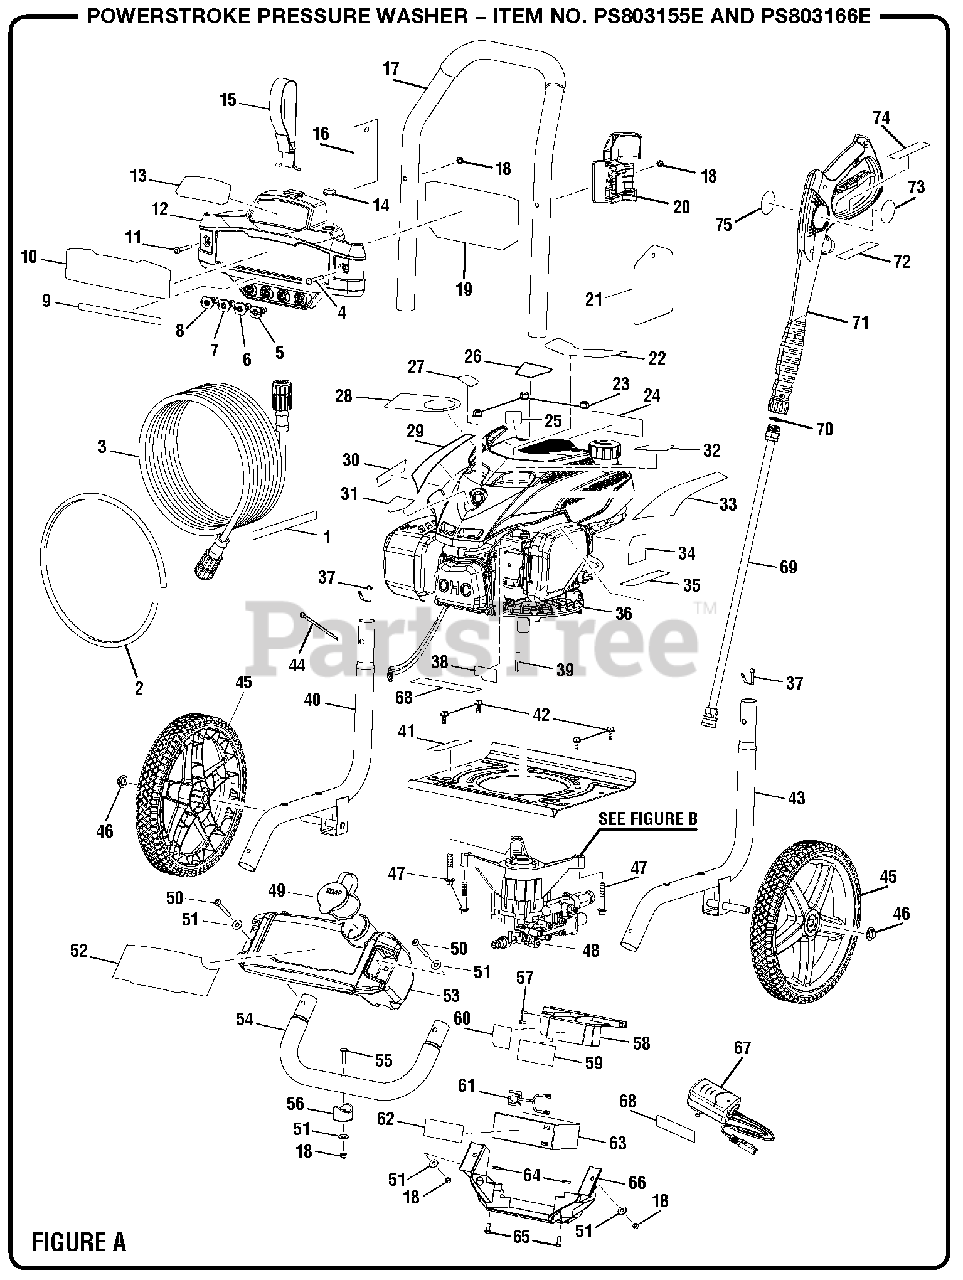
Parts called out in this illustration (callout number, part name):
1	Hose Label
2	Chemical Siphon Tube
3	Hose (30 ft.)
4	Bolt (M6 x 48 mm, Button Hd.)
5	Soap Nozzle
6	40deg Deg Nozzle
7	25deg Deg Nozzle
8	15deg Deg Nozzle
9	Nozzle Selection Label
10	Powerstroke/Yamaha Label
11	Bolt (M6 x 42 mm, T-30 Torx Pan Hd.)
12	Hose & Nozzle Holder Assembly
13	Performance Label
14	Rubber Grommet
15	Hose Holder Strap
16	Danger Hang Tag
17	Handle Assembly
18	Lock Nut (M6)
19	Quick Start Label
20	Wand Holder
21	Standard Nozzle Hangtag
22	Yamaha Recoil Label
23	Flange Lock Nut (M8)
24	Danger Label
25	Add Oil Label
26	E85 Label
27	Vent Label (Left)
28	Oil Dipstick Hang Tag
29	Electric Start Label (Left)
30	Hot Surface Label
31	Start Label
32	Vent Label (Right)
33	Electric Start Label (Right)
34	Fuel Valve Label
35	Inquiries Label
37	Handle Spring Clip
38	Choke Label
39	Output Shaft Key
40	Left Frame Assembly
41	Combustion Warning Label
42	Flange Bolt (M6 x 16 mm)
43	Right Frame Assembly
46	Wheel Cap
47	Bolt (M8 x 60 mm, Flange Hex Hd.)
48	Pump (See Figure B)
49	Soap Tank Cap
50	Screw (M6 x 55 mm, T3 Torx Pan Hd.)
51	Washer (1/4 in.)
52	Detergent Tank Label
53	Soap Tank
54	Front Frame Assembly
55	Bolt (M6 x 48 mm, T-30 Torx Hd.)
57	Screw (M4 x 12 mm, T-20 Torx Hd.)
58	Battery Hold Down
59	Charge Warning Label
60	Battery Bracket Label
61	Battery and Charger Wire Harness
62	Battery Replacement Label
65	Bolt (M6 x 16 mm, T30 Torx Pan Hd.)
66	Battery Mount Bracket
67	Battery Charger
68	Battery Cordwrap Label
69	Wand Assembly
71	Trigger Handle Assembly
72	Trigger Handle Warning Label (En)
73	Trigger Handle Warning Label (French/Spanish)
74	Trigger Handle Rating Label
75	Trigger Wand Logo Label
